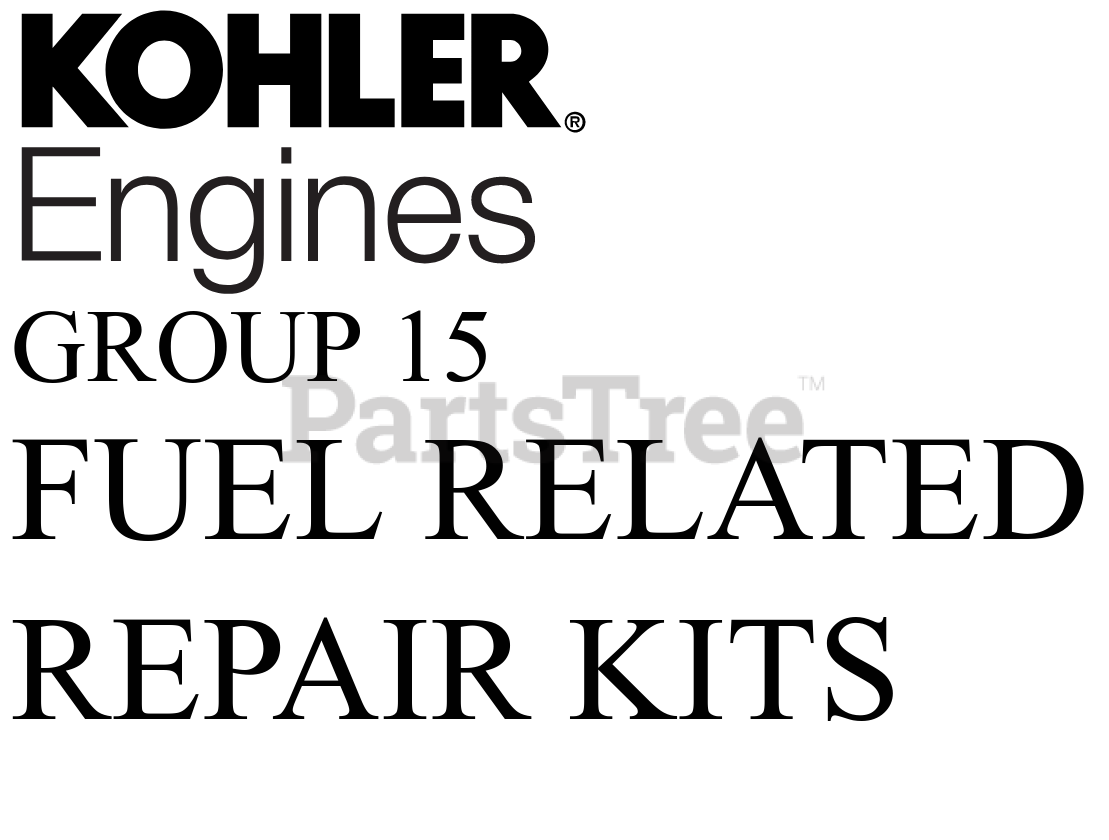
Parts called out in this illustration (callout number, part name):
NI	KIT, SOLENOID VALVE REPAIR
NI	KIT, OVERHAUL
NI	KIT, FLOAT REPAIR-DISCONTINUED
NI	KIT, HIGH ALTITUDE (4000 - 8000')
NI	KIT, HIGH ALTITUDE (ABOVE 8000')
NI	KIT, CHOKE
